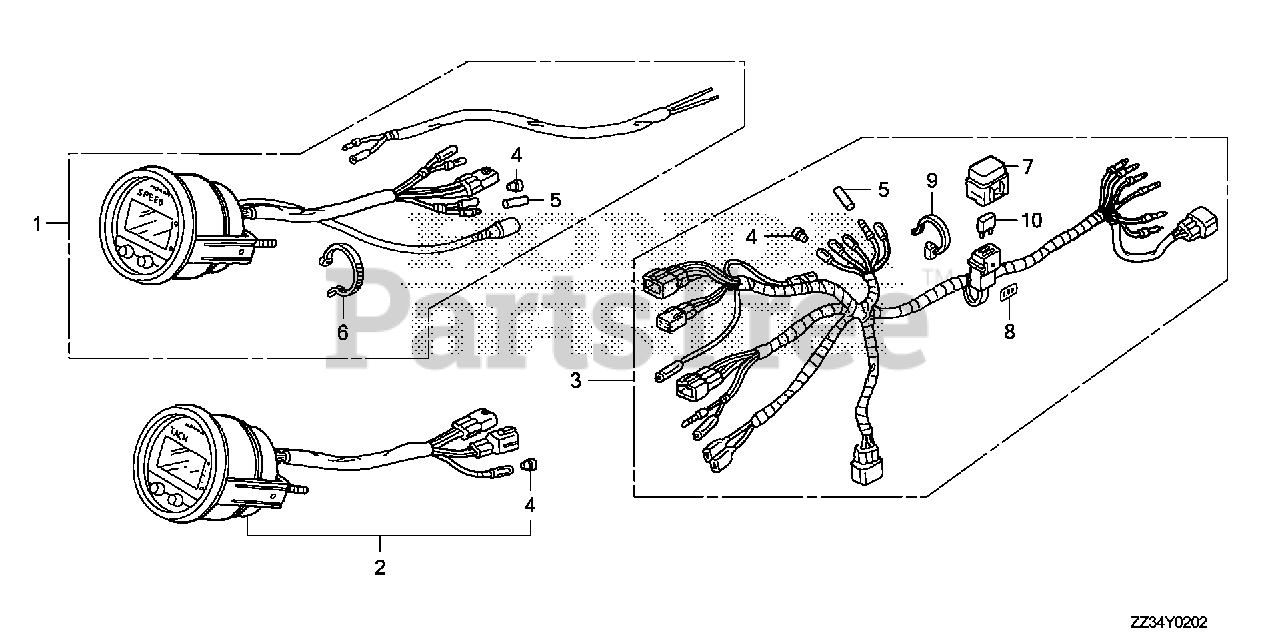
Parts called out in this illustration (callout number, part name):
1	SPEEDOMETER KIT (DIGITAL)(USA) (NOT AVAILABLE)
2	METER KIT, TACHO (DIGITAL)(USA) (NOT AVAILABLE)
2	METER KIT, TACHO (DIGITAL) (USE FOR 32540-ZY3-800/801)
3	HARNESS ASSY., METER (A)(DIGITAL)
4	PLUG, CONNECTOR (INNER)
5	PLUG, CONNECTOR (OUTER)
6	BAND (BLACK 3.5X140)
7	COVER ASSY., FUSE (7.5A)
8	MARK, FUSE (7.5A)
9	TIE, CABLE
10	FUSE, BLADE (7.5A)
